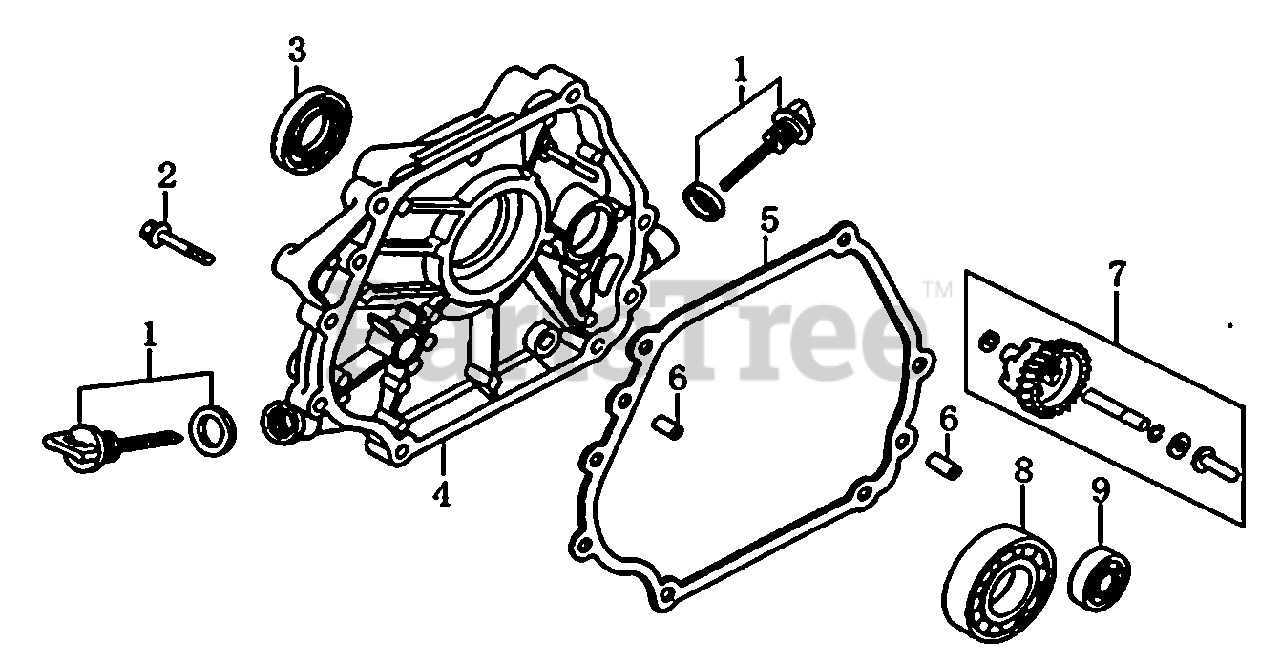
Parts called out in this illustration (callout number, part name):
1	CAP ASSY
2	BOLT, FLANGE 8X40
3	SEAL, OIL
4	COVER, CRANKCASE
5	GASKET, CRANKCASE COVER
6	PIN, DOWEL
7	GOVERNOR ASSY.
8	BEARING, BALL 6207
9	BEARING, BALL 6202
